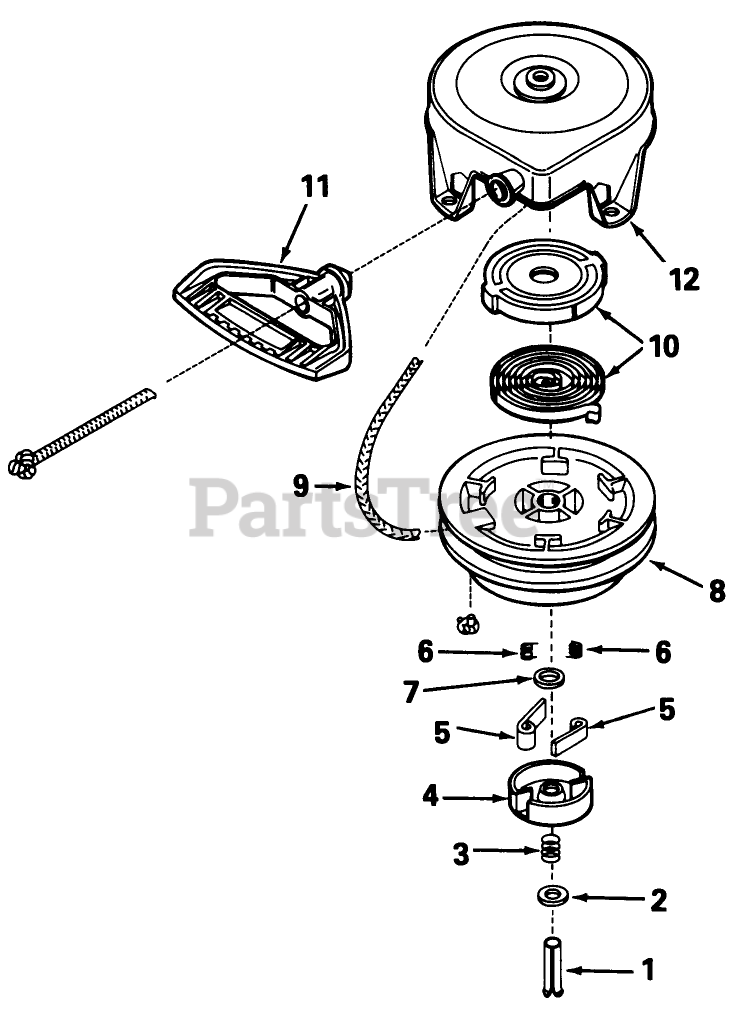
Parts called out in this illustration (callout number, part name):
1	Pin, Spring (Incl. Ref. #7)
2	Washer
3	Brake Spring
4	Retainer
5	Dog-Starter
6	Spring-Dog
7	Washer
8	Pulley
9	Rope-Starter
10	Spring Keeper Assy.
11	Handle-Starter, Mitten Grip
12	Housing Assy., Starter
